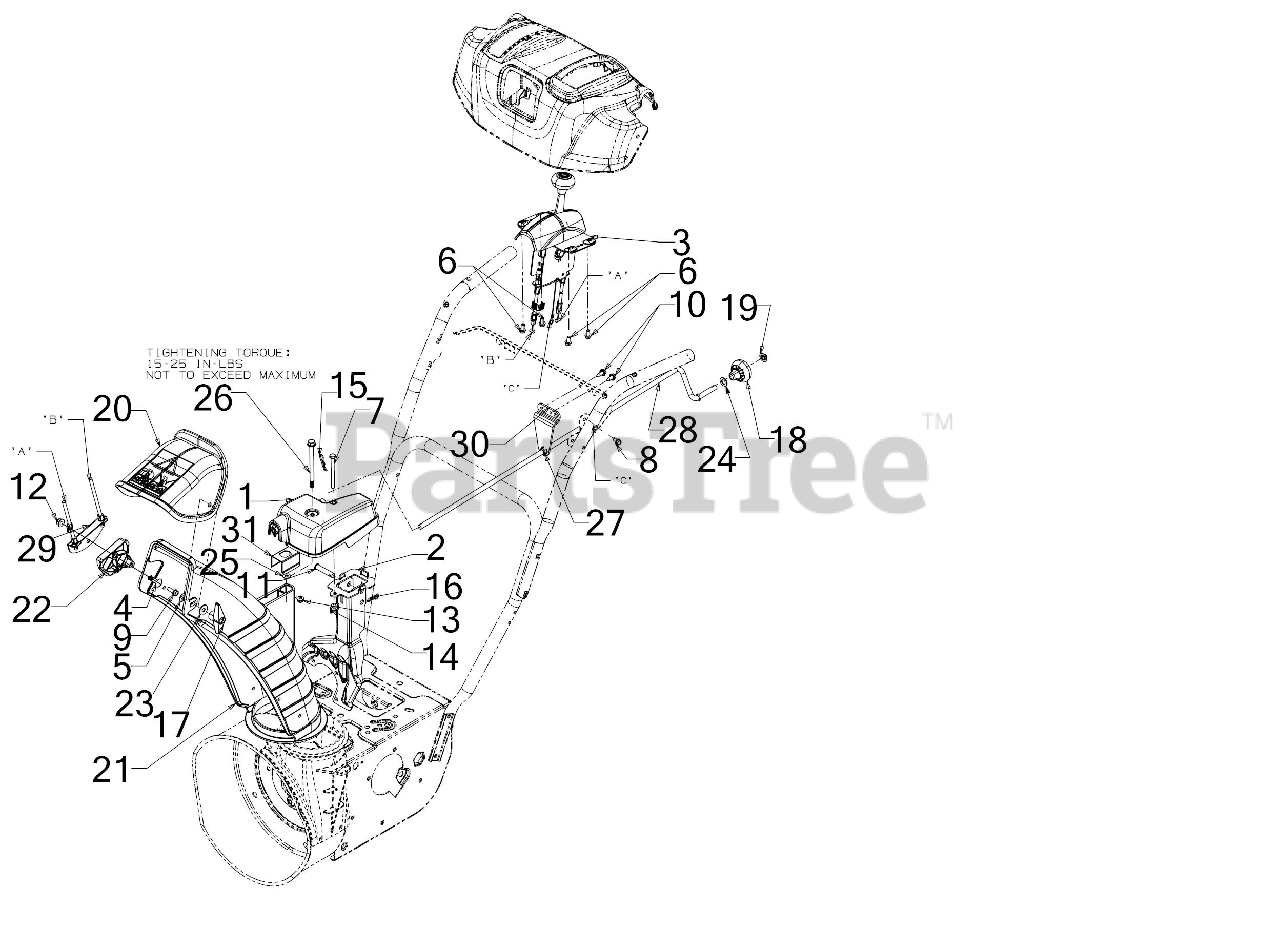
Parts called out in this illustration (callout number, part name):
1	WORM GEARBOX ASSEMBLY
2	CHUTE SUPPORT BRACKET ASSEMBLY
3	2-WAY TALL CHUTE CONTROL ASSEMBLY
4	CARRIAGE BOLT 5/16-18 x 1.50
5	CARRIAGE BOLT 5/16-18 x 1
6	HEX SCREW 1/4-15 x .50
7	SCREW 1/4-20 x 3.0 GR5
8	SCREW 1/4-20 X.500
9	SCREW 1/4-15 x .750
10	SCREW 1/4-20X.625
11	CLEVIS PIN 3/8 x 1.87
12	FLANGE LOCK NUT 5/16-18
13	FLANGE LOCK NUT
14	WING NUT 1/4-20
15	INTERNAL COTTER PIN
16	BOW TIE COTTER PIN 1/4-5/16
17	WING NUT KNOB
18	SHIFT KNOB
19	PUSH NUT
20	UPPER CHUTE
21	LOWER CHUTE 5" DIA
22	CABLE CHUTE GUIDE
23	FLAT WASHER
24	FLAT WASHER
25	FLAT WASHER
26	SHOULDER SCREW
27	BUSHING .380 ID
28	CHUTE CRANK
29	CABLE BRACKET
30	ROD SUPPORT BRACKET
31	CHUTE BRACKET
